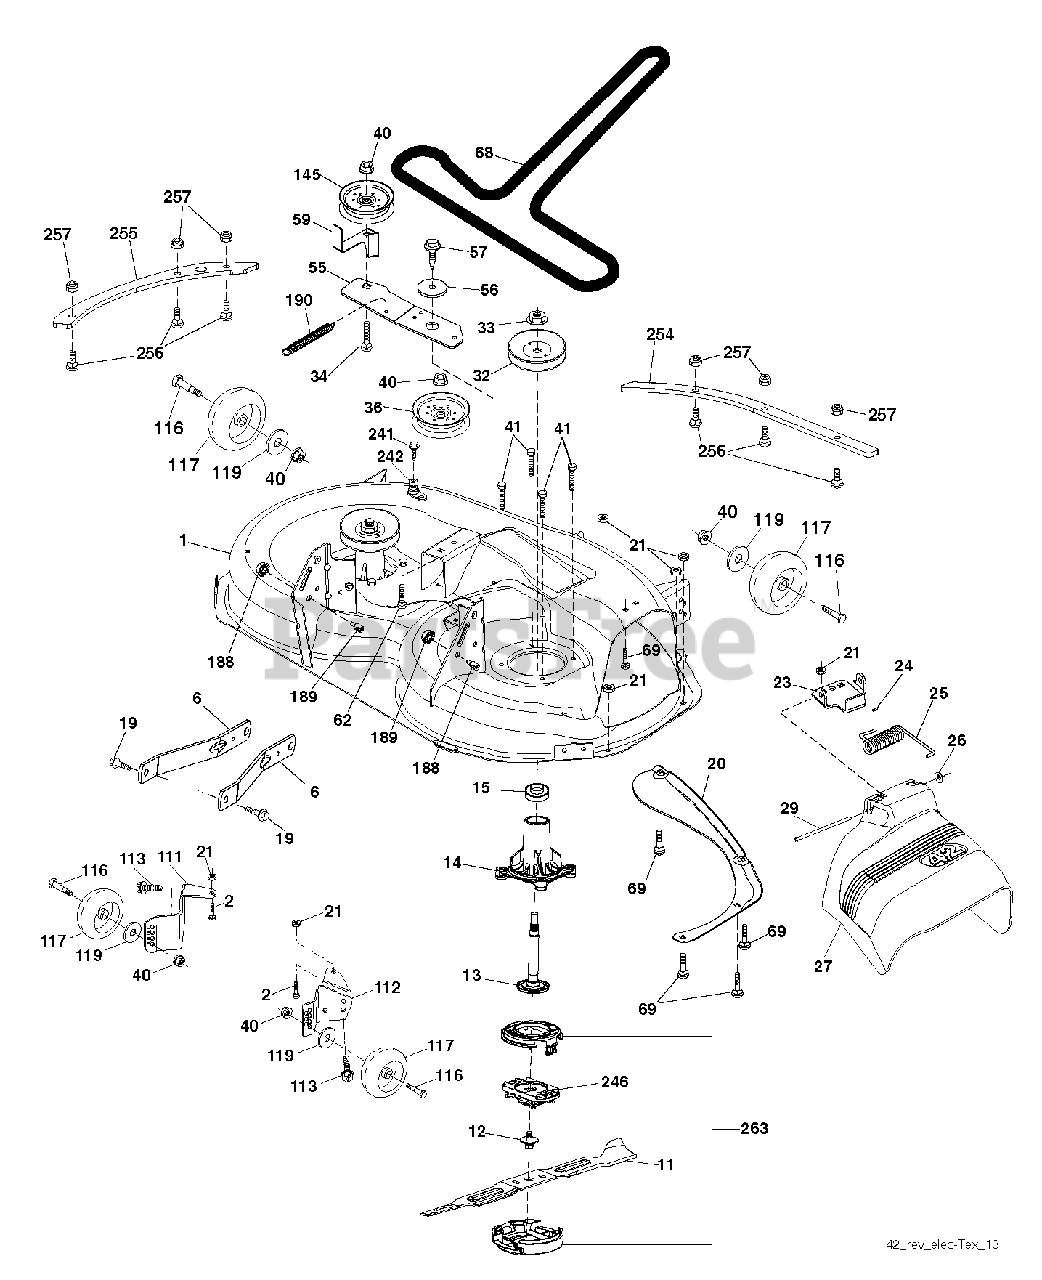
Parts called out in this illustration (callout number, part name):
1	DECK.WELDMNT.42"GREYMS498
2	BOLT 5/16-18 X3/4 ZN/YEL GR 5
6	ARM.SUSPENSION.MOWER.R
11	42" HI-LIFT BLADE
12	SCREW.SEMS.7/16-20X1.HEX.HEAD
13	SHAFT ASM.REV.TALL.N/GREASEBL
14	HOUSING.MANDREL.REV.TALL.N/GRS
15	BEARING.MANDREL.TOP.EXTENDED
19	BOLT.SHOULDER
20	BAFFLE.VORTEX
21	LOCKNUT
23	BRKT.DEFLECTOR.38"2005+
24	CAP-SLEEVE LT
25	SPRING.TORSION.DEFLECT
26	NUT PUSH M
27	SHIELD.DEFLECTOR.MOWER.42"BLAC
29	ROD.HINGE
32	PULLEY/MANDREL
33	NUT.FLANGE.LOCK.TOP
34	BOLT.3/8-16X1.50
36	PULLEY.IDLER.2006
40	NUT LOCK FLG 3/8-16 UNC
41	BOLT.HEX.WASHR.HED.313-18X1.19
55	IDLER.ARM.42"
56	SPACER.RETAINER
57	SCREW 3/8-16X1
59	GUARD, BELT
68	BELT V SECONDARY
69	BOLT
111	BRKT.WHEEL.GAUGE.LH.42"
112	BRKT.WHEEL.GAUGE.RH.42"
113	BOLT.5/16HEX.WHS.HD
116	BOLT M
117	WHEEL.GAGE.HALF.SPOKED
119	WASHER
145	PULLEY.IDLER.48"PRIMARY
188	STUD.FASTNER.W/ANTI-ROTATE
189	NUT LOCK HEX FLANGE 5/16-18
190	SPRING.MOWER.DRIVE.ELECTRIC
241	SCREW.TT.#10-32X.5.3/8.FLANGE
242	PORT.WASHOUT
246	HOLDER.BLADE.REVOLUTION
254	PLATES.RENFRC.42DECK.PT431FRNT
255	PLATES.RENFRCE.42DECK.X431SIDE
256	RHSNB, 1/4-20 X 1, GR5
257	NUT T
263	CAP.REVOLUTION ASM
